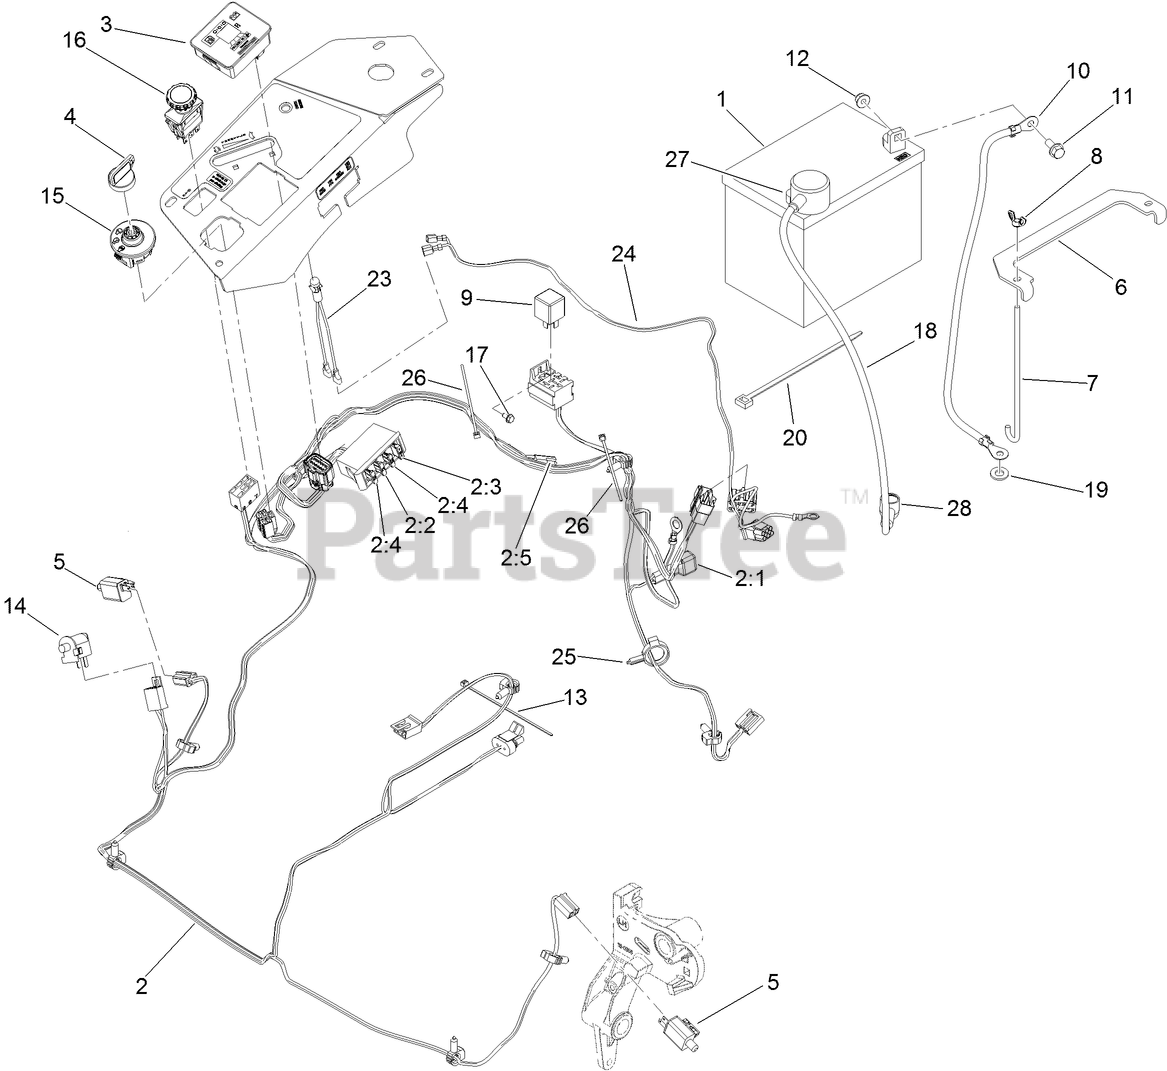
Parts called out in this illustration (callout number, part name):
1	BATTERY-DRY
2	HARNESS-WIRE, MAIN
2:2	FUSE-BLADE, 10 AMP
2:3	FUSE-BLADE, 15 AMP
2:4	FUSE-BLADE, 25 AMP
2:5	CAP-PLUG
3	FUEL/HOUR METER ASM
4	KEY-IGNITION
5	SWITCH
6	STRAP-TIE DOWN, BATTERY
7	BOLT-HOLDDOWN
8	WINGNUT
10	CABLE-BATTERY, NEGATIVE
11	SCREW-HHF
12	NUT-HF, NI
13	TIE-CABLE
14	SWITCH-BAIL
15	SWITCH-IGNITION
16	SWITCH-PTO, 10 AMP
17	SCREW-HWH
18	CABLE-BATTERY, POSITIVE
19	WASHER-FLAT
20	TIE-PLASTIC
23	INDICATOR-LED, RED
24	HARNESS-LIGHT, INDICATOR
25	CLAMP-HOSE
26	TIE-CABLE
27	INSULATOR-BATTERY
28	INSULATOR-SOLENOID
